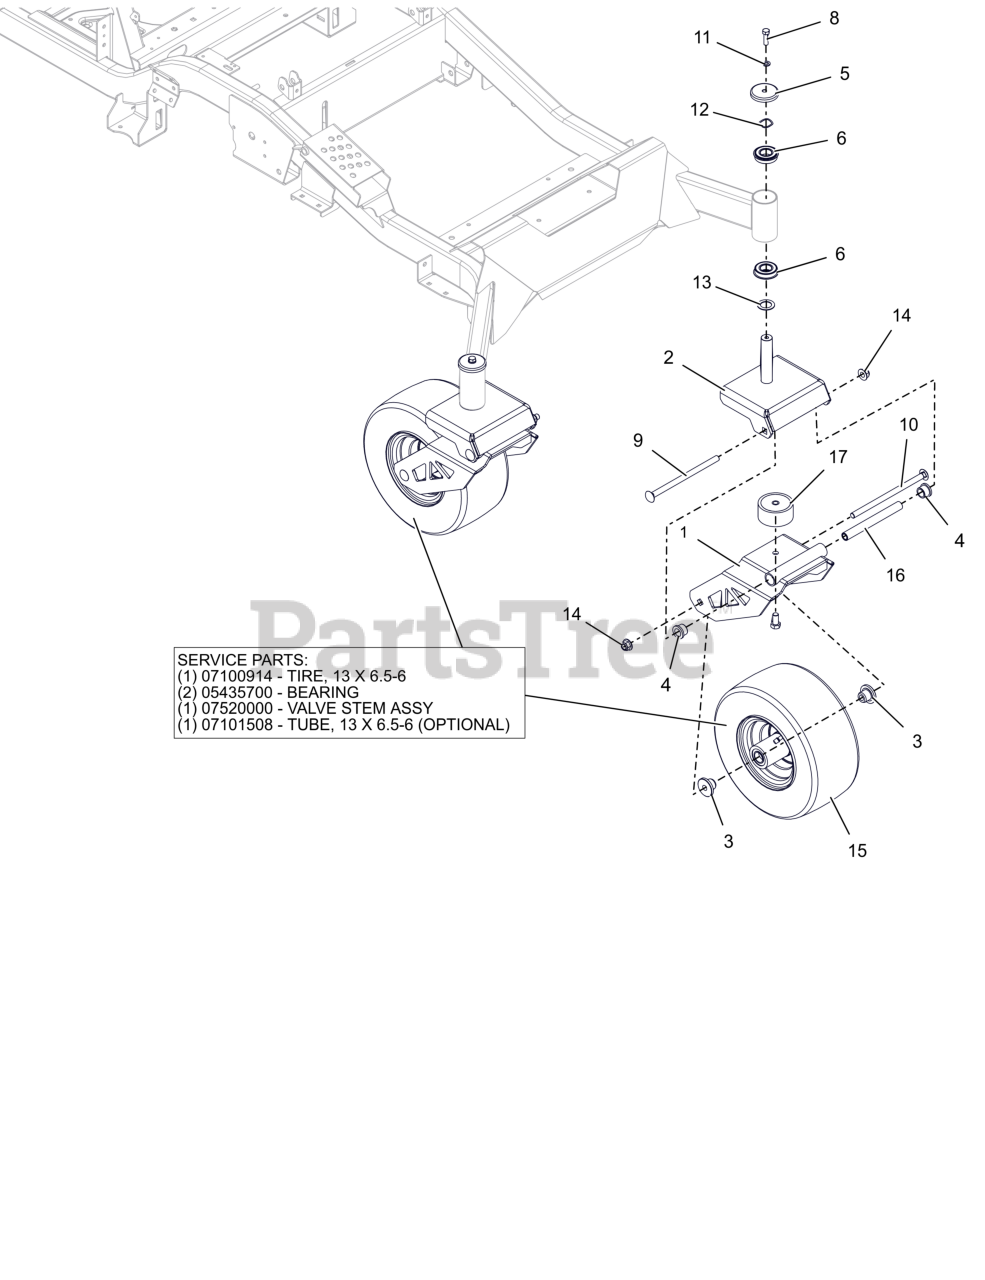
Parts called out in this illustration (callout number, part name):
1	WLDMT- LOWER SUSPENSION (ORG)
2	WLDMT- UPPER SUSPENSION FORK
3	SPACER, FRONT WHEEL
4	BUSHING, FLANGE .75X.75X1.0
5	SHIELD, AXLE BEARING
6	BEARING, BALL -2.000 OD X 1.000 ID X .5625 W/RING
8	BLT- HEX .38-16X1.25 G5 ZB500
9	BLT, RHSN .50-13X8.50 G5 ZCC
10	BLT-RHSN .50-13X9.00 G5 ZCC NS
11	WSHR-LK-REG .375X.094 ZB500
12	WSHR-WAVE 1.0X1.25X.028 .145FH
13	WSHR-HRD-THRS 1.007X1.542X.062
14	NUT,NYL-FLG .50-13 GF ZCC
15	ASM, TIRE/WHEEL 13 X 6.50-6 BLK RIM
15	LAWN TIRE FRONT, 13X6.50-6 SMOOTH
15	BRG, 25MM ID X 52MM OD X 15MM
15	VALVE STEM ASS'Y
15	TIRE TUBE, 13/6.5-6 4 PLY TR87 90 BENT VALVE
16	ROD- FORK PIVOT
17	SPCR- RUBBER SUSPENSION
